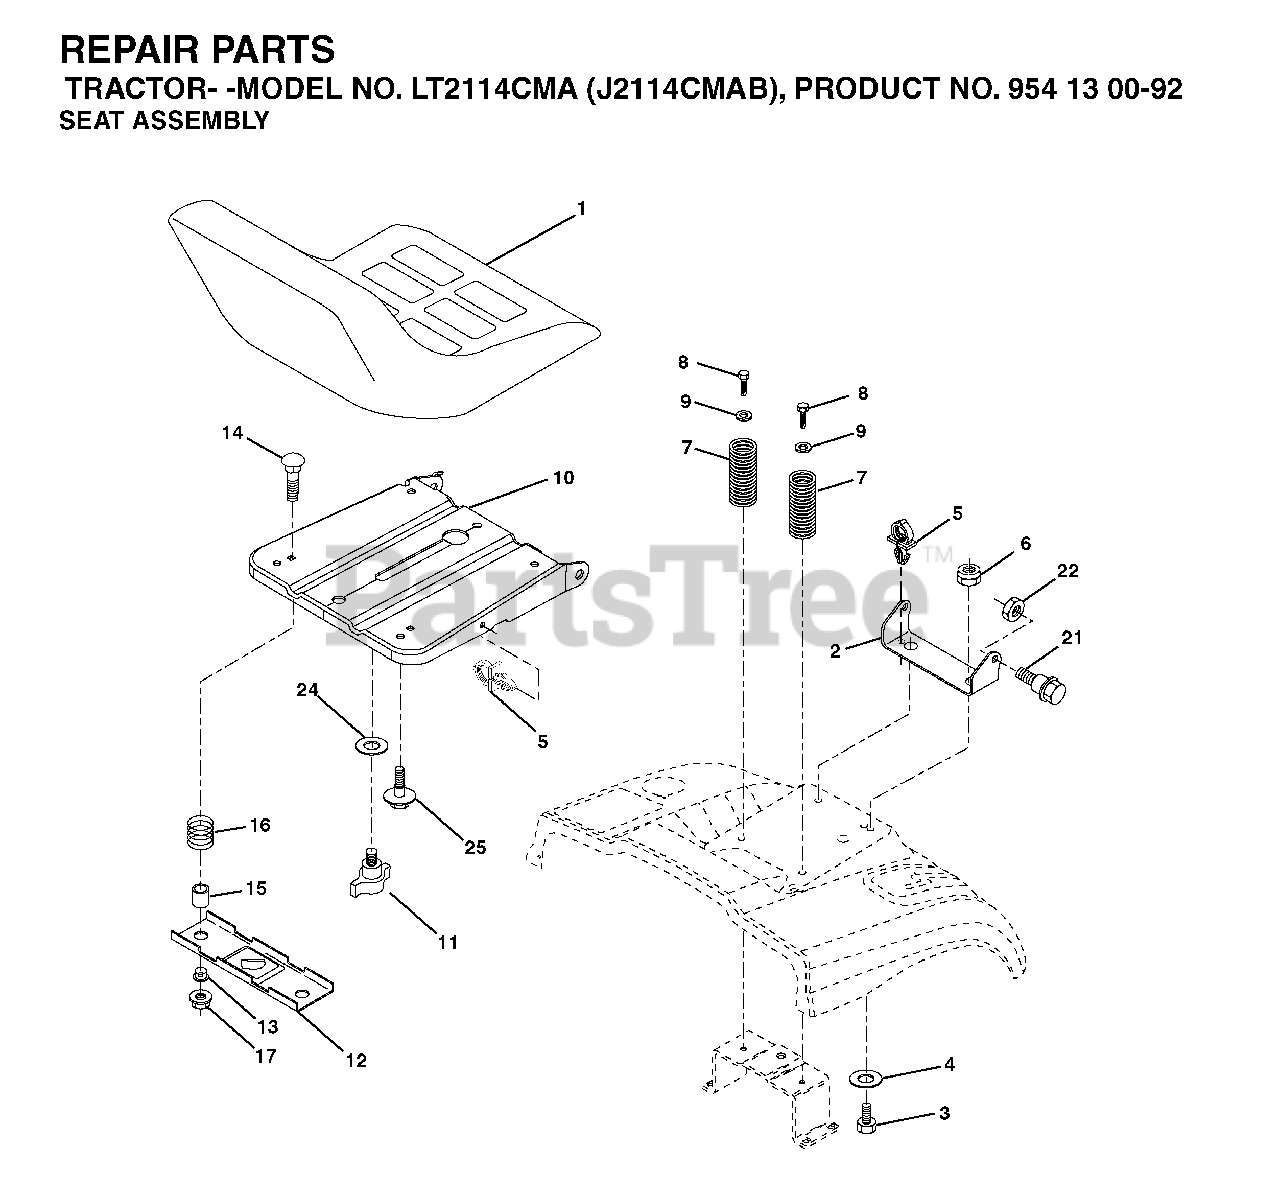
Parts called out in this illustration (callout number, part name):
2	SEAT PIVOT BRKT
4	WASHER PM
5	PUSH CLIP
6	NUT
7	SPRING COMPRESSION
8	SCREW 3/8-16X1
9	WASHER
10	PAN SEAT
11	KNOB.SEAT.ADJ.WINGNUT
12	BRKT SWITCH
14	BOLT.ROUND.HEAD.SQUARE.NECK
15	SPACER SPLIT 28X.96
17	NUT T
21	BOLT.SHOULDER.5/16-18
22	NUT.71038.31-18.HEX.NYLOCK
25	BOLT,SHOULD
